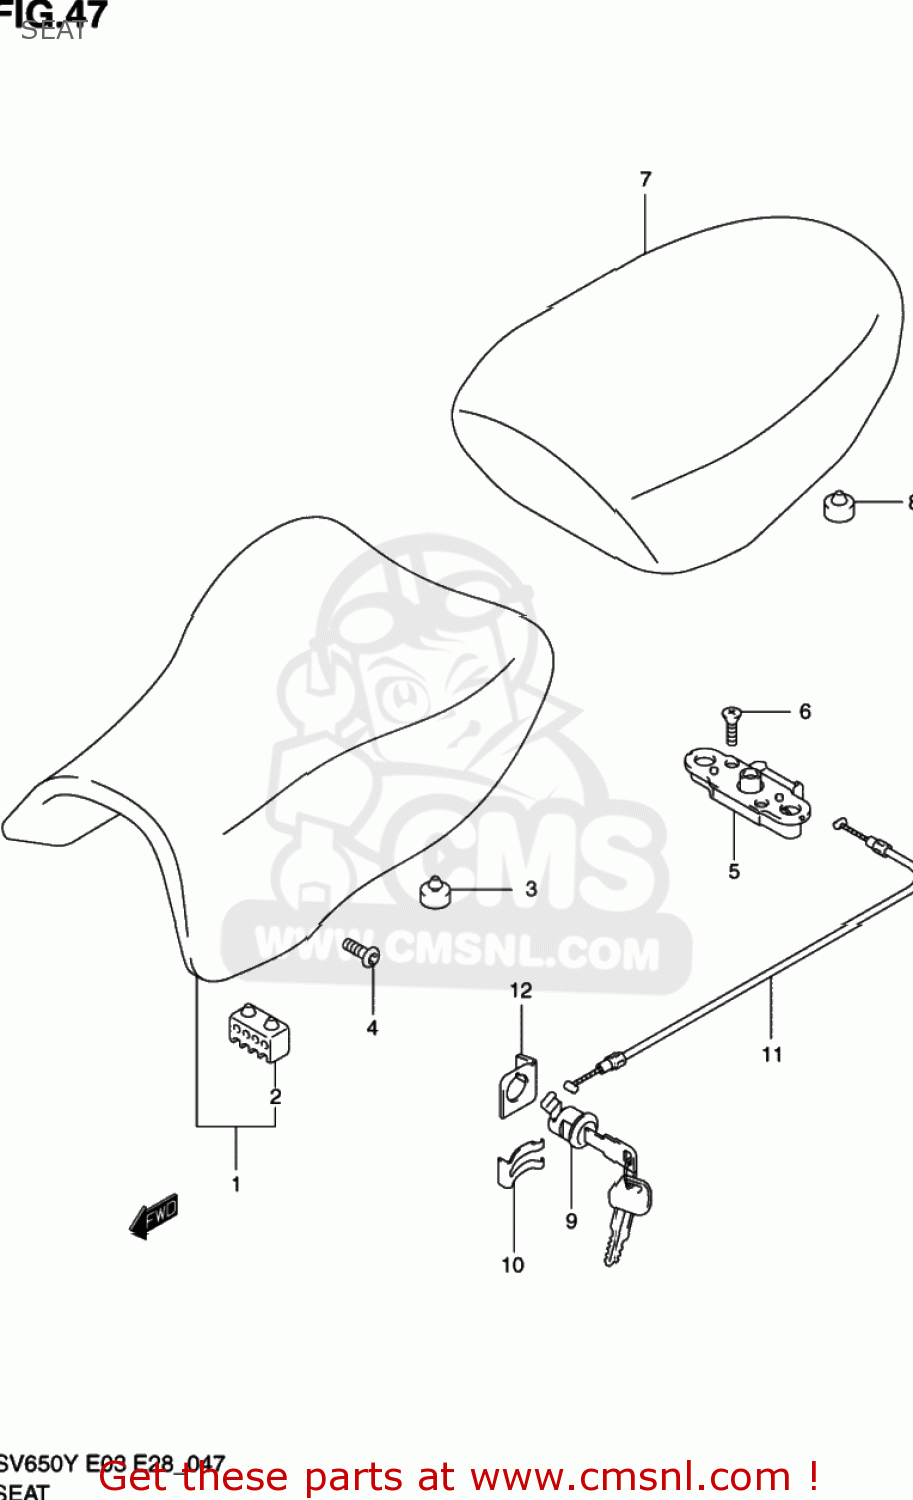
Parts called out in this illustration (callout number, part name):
1	SEAT ASSEMBLY
2	CUSHION,SEAT(40X20X15)
3	CUSHION(11.5X22X20)
4	BOLT(6X18)
5	BRACKET,SEAT SUPPORT,RIGHT
6	SCREW
7	SEAT ASSY,PILLION
8	CUSHION
9	LOCK SET,SEAT
10	PLATE,SEAT LOCK ASSY
11	CABLE,SEAT LOCK
12	GUIDE,SEAT LOCK CABLE
